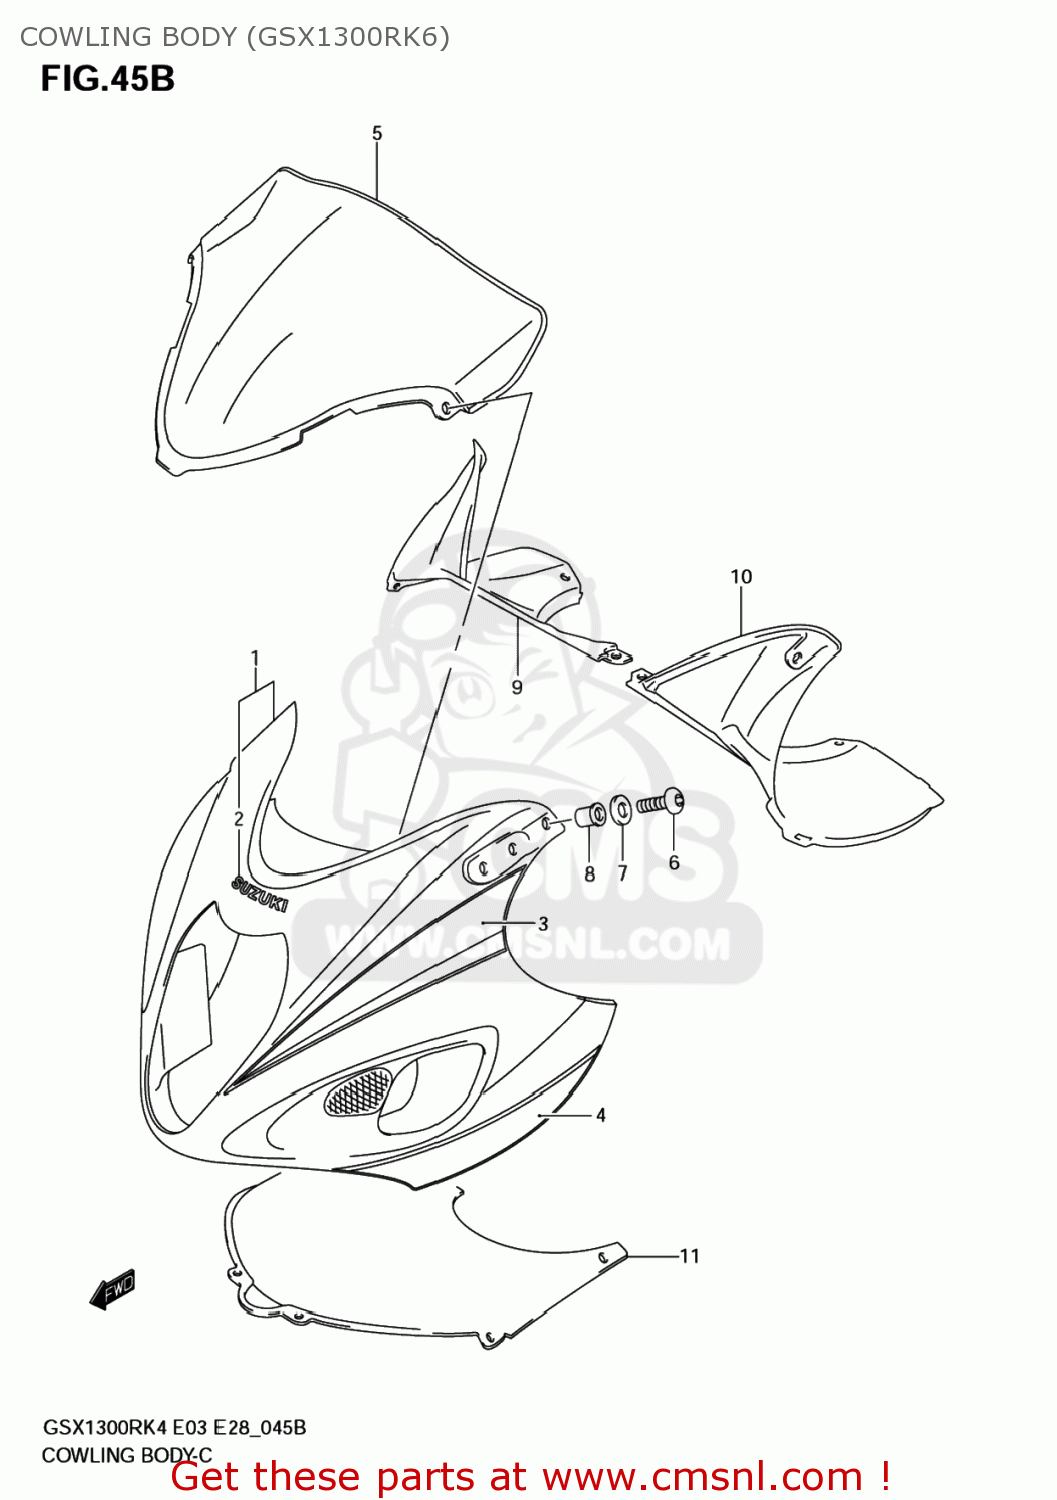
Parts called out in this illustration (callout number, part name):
1	COWLING ASSY,BODY
2	EMBLEM,SUZUKI
3	TAPE SET,BODY UPR
4	TAPE SET,BODY SIDE
5	WINDSCREEN
6	SCREW(5X14)
7	WASHER
8	NUT
9	PANEL,UPR,R
10	PANEL,UPR,L
11	COVER,BODY COWLING
